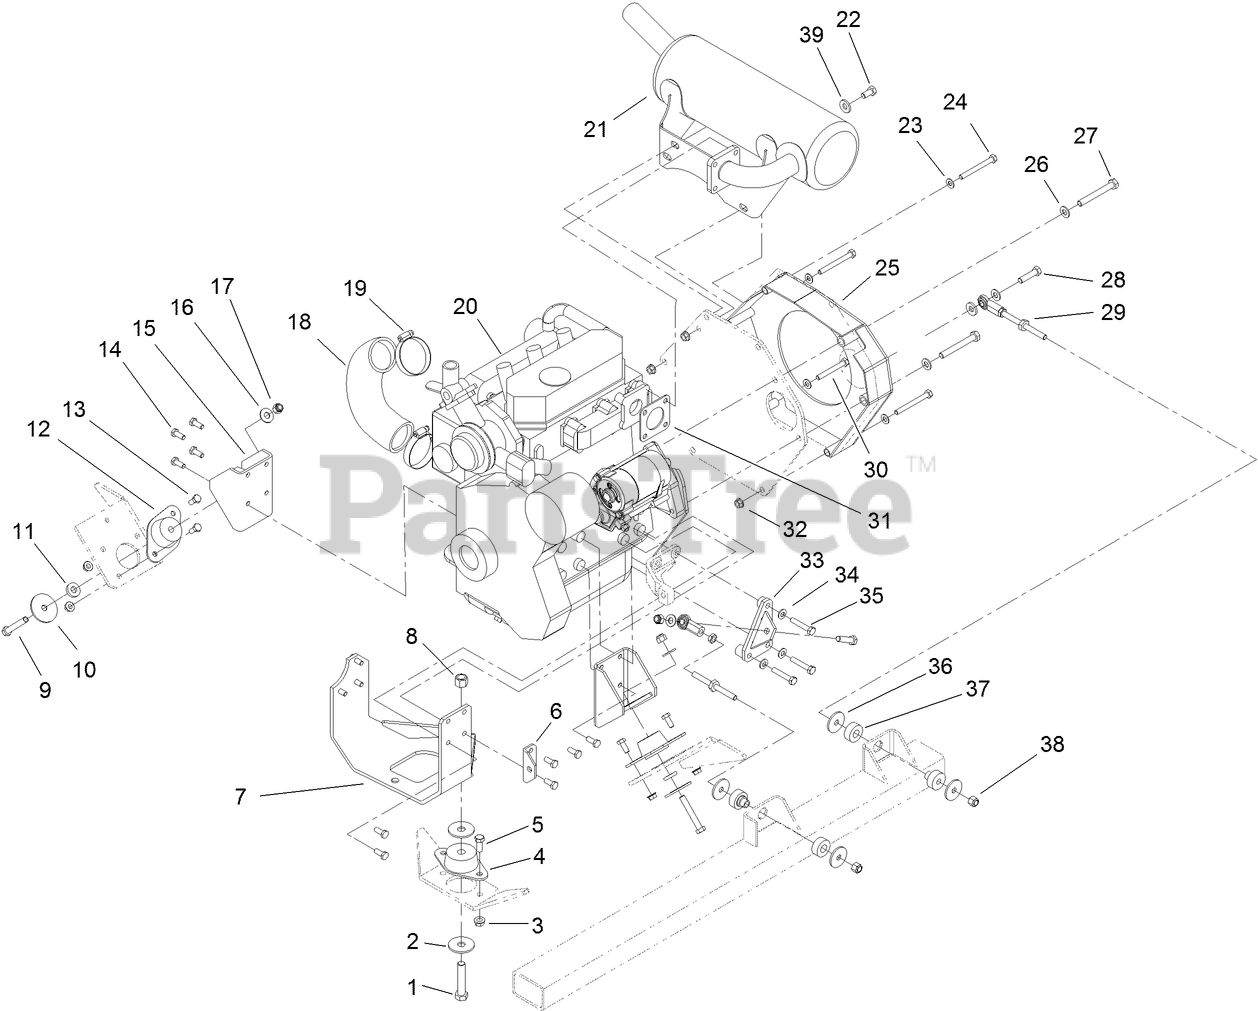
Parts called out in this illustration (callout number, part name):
1	SCREW-HH
2	WASHER-THRUST
3	NUT-HHF, WHIZ
4	ISOLATOR-REAR
5	SCREW-HH
6	BRACKET-GROUND
7	REAR ENGINE MOUNT ASM
8	NUT-LOCK, NI
9	SCREW-HH
10	WASHER-FLAT
11	WASHER
12	ISOLATOR-SIDE
13	SCREW-HH
14	SCREW-HH
15	LH AND RH ENGINE MOUNT ASM
16	WASHER-FLAT
17	NUT-LOCK, NI
19	CLAMP-HOSE
20	ENGINE-DAIHATSU
21	MUFFLER KIT
22	WASHER-BELLEVILLE
23	WASHER-PLAIN
24	SCREW-HH
25	COVER-FLYWHEEL
26	WASHER-FLAT
27	SCREW-HH
28	SCREW-HH
29	BALL JOINT LINK ASM
30	SCREW-HH
31	GASKET-MUFFLER
32	NUT-HF
33	BRACKET-ENGINE, FRONT
34	WASHER-SPRING
35	Screw-HH
36	WASHER
37	ISOLATOR-LINK
38	NUT-LOCK
39	SCREW-CAP
